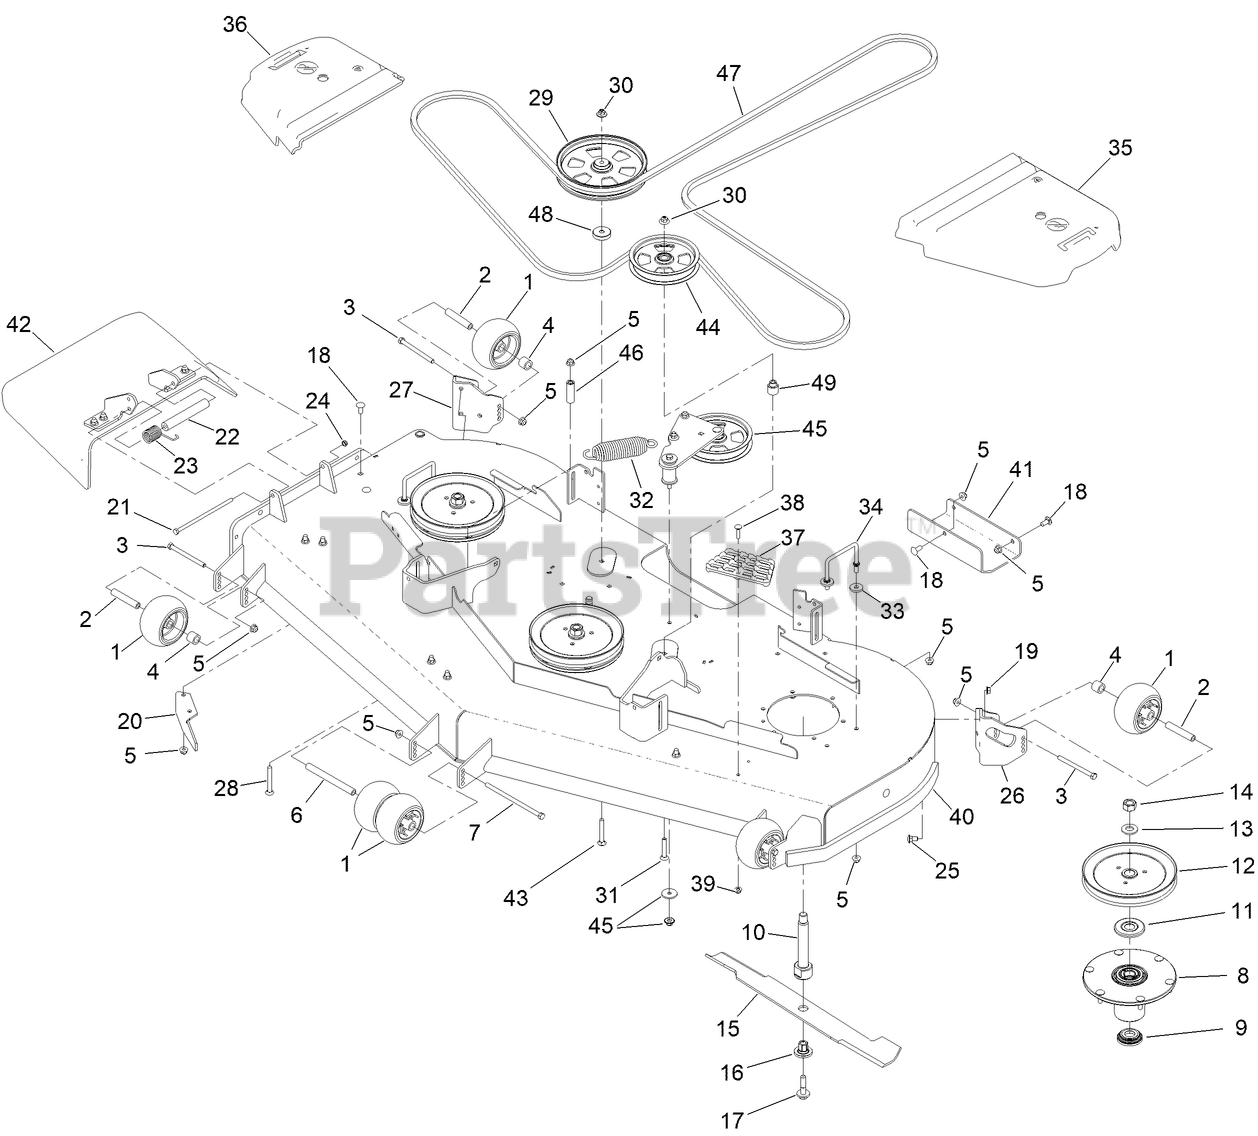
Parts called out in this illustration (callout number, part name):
1	ROLLER-SCALP, ANTI
2	TUBE-SPANNER
3	SCREW-HH
4	TUBE-SPACER
5	NUT-HF, NI
6	SPACER-WHEEL
7	SCREW-HH
8	SPINDLE ASM
9	GUARD-BOTTOM
10	SHAFT-SPINDLE
11	GUARD-BEARING, TOP
12	SHEAVE-DRIVE, BLADE
13	WASHER
14	NUT-HEX
16	BUSHING-HEX
17	SCREW-SEMS
18	SCREW-CARR
19	NUT-HHF, WHIZ
20	BAFFLE-DISCHARGE
21	SCREW-HH
22	SPACER
23	SPRING-TORSION
24	NUT-LOCK, NI
25	SCREW-CARR
26	MOUNT-WHEEL, LH
27	MOUNT-WHEEL, RH
28	SCREW-HHF
29	PULLEY-IDLER,FLAT
30	NUT-FLANGE, NI
31	BOLT-CARR, SHORT NECK
32	SPRING-EXTENSION
33	WASHER
34	WIREFORM-COVER
35	COVER-BELT, LH
36	COVER-BELT, RH
37	STEP-DECK
38	SCREW-CARR
39	NUT-HF, NI
40	DECK DECAL ASM
41	PLATE-SKID
42	RUBBER DEFLECTOR ASM
43	SCREW-CARR
44	PULLEY-IDLER, FLAT
45	IDLER ARM ASM
46	SPACER-HYDRO
47	BELT, V-5V X 206.6"
48	SPACER-PULLEY
49	BUSHING, IDLER
